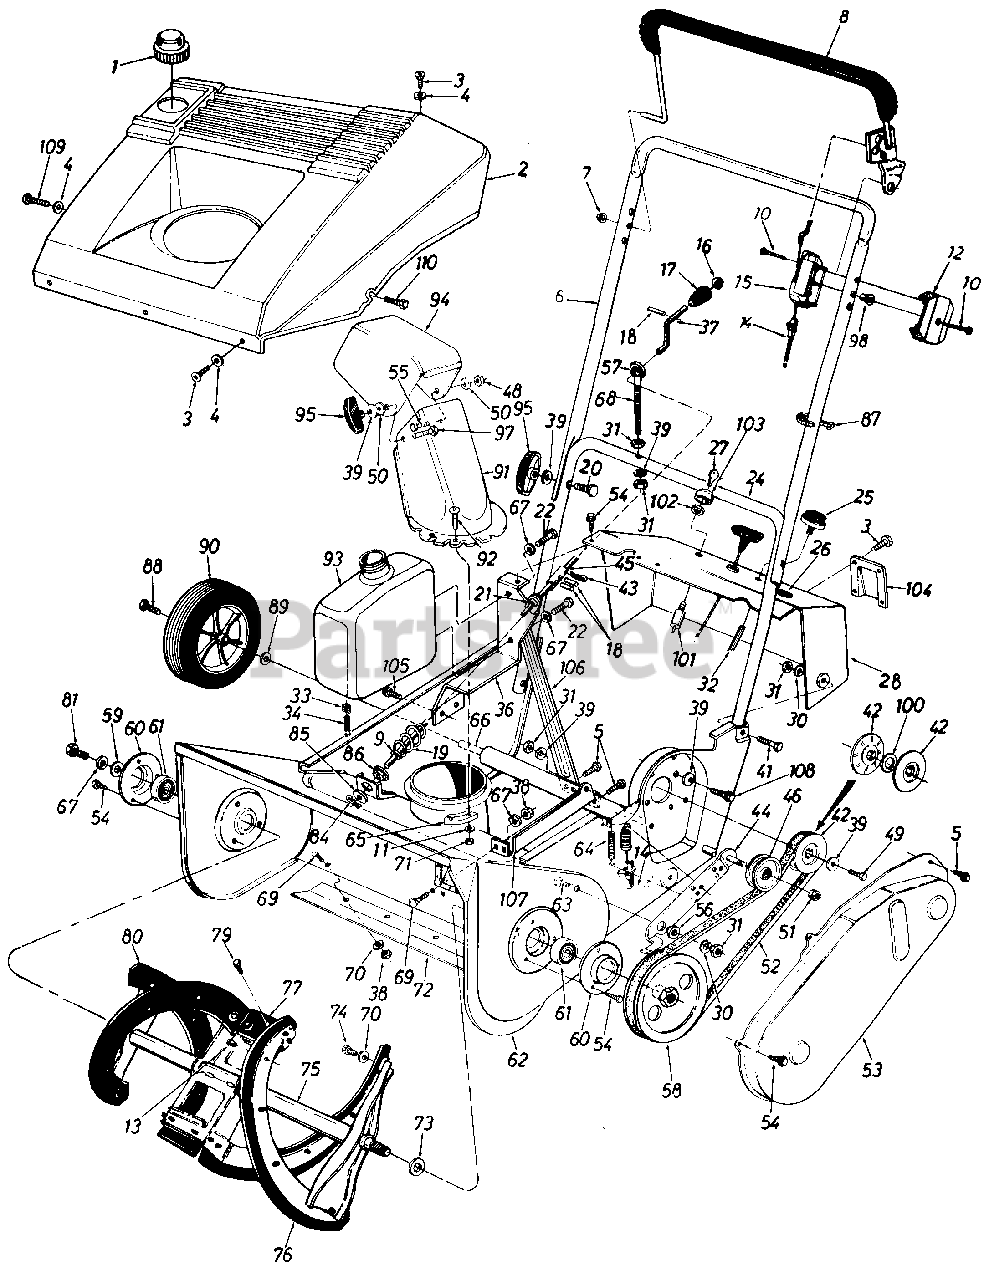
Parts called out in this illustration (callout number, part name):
1	Gas Tank Cap
2	Shroud
3	Hex B-Tap Scr. #10 x .5" Lg.
4	Fl-Wash. 203" I.D. x 41'
5	Hex L-Wash. Hd. AB-Tap 1/4 x 62" Lg.
8	Control Handle Ass'y.-L.H.
9	Fl-Wash. .385" I.D. x .62"
10	Truss Mach Hi-B Tap Scr. #12 x 1.5" Lg.
11	Fl-Wash. .281" I.D. x .5" O.D.
12	Control Panel Halt
13	Pop Rivet .188" Dia.
14	Clutch Cable 35n Lg.
15	Control Panel Half
16	Push Cap 3/8" Rod
17	Knob-3/8" Oia. Hole
18	Roll Pin 1/8" Dia. x .63" Lg.
19	Lower Chute Crank Ass'y.
20	Curvled Carriage Bolt 5/16-18 x 1.75n Lg.
21	Chute Crank Grommet
22	Hex Bolt 20 x 5" Lg.
26	Plastic Plug
31	Hex Nut 5/16-18 Thd.
32	Primer Hose-9" Lg.
33	Hose Clamp-1/2" O.D.
34	Gas Line-16" Lg.
36	Gas Tank Support Brkt.
38	Hex Jam Nut 1/4-20 Thd.
39	Bell-Wash. .345" I.D. x .88
41	Hex Bolt 6/16-18 x 1.5" Lg.
42	3/8" "V".-Pulley Half .625" I.D. x 6.0" O.D.
43	Cotter Pin 3/32" Dia. x 1" Lg.
46	Fl-ldlet w/Flanges 2.12 O.D.
48	Hex L-Nut 5/118 Thd.
49	Hex Bolt 5/16-24 x .75 Lg.
50	Fl-Wah. .344 I.D. x 1.25
51	Hex Patch L-Nut 3/8-24 Thd.
52	"V"-8elt
54	Hex B-Tap Scr. 1/4" x .38 Lg.
55	Carriage Bolt 5/16-18 x .75
56	Shld. Spacer .50" Dia. x .27"
57	Plastic 8ushing .38 I.D.
58	1/2" "V -Pulley 1/2-20 L.H. x 6"
59	Fl-Wash. 1/" I.D. x .93" C.D.
64	Extension Spring 1.12' Lg.
65	Chute Flange Keeper
66	Wheel Axle 20.6 Lg.
67	L-Wash. 1/4" 1 D.
68	Eyebolt
69	Carriage Bolt 1/4-20 x .50
70	Fl-Wash. .281" I.D. x .73
71	Hex L-Nut 1/4-20 Thd.
72	Shave Plate
73	Fl-Wash. 510" I.D. x 1.0" O.D.
74	Hex Wash. B-Tap Scr. 1/4 x .62"
76	Rubber Spiral-L.H.
77	Rubber Paddle
79	Hex Wash. 3-Tap Scr. #10 x .62" Lg.
80	Rubber Spiral-R.H.
81	Hex Wash. TT-Tap Cl-Scr. 1/4-20 x 75" Lg.
84	Cotter Pin 3/32" Dia. x .75
85	Fl-Wash. .406" I.D. x 1.251'
86	Hex Bushing .385" I.D.
87	Cable Tie
88	Hex Tap Scr. 3/8-24 x . 5" Lg.
89	Fl-Wash. .510' I.D. x .75"
90	7" Wheel & Tire Ass'y.
91	Lower Chute
92	Truss Mach. Scr. 1/-20 x .75"
93	Fuel Tank-Two Qt.
94	Upper Chute
95	Knob Handle Ass'y.
97	Carriage Bolt 5/118 x 1"
98	Control Disc Pin
100	Fl-Wash. .635" I.D. x .93' O.D.
101	Key Switch
102	Ignition Switch Nut 5/8-32 Thd.
103	Ignition Switch Cap
104	Choke Cover
105	Hex Wash. Hd. Tap Scr. 1/4-5" Lg.
108	Hex Bolt 51118 x 5/8" Lg.
109	Pan Hd. Tap Scr. #10 x 1.25" Lg.
110	Hex Wash. Hd. Tap Scr. 1/ 20 x l" Lg.
